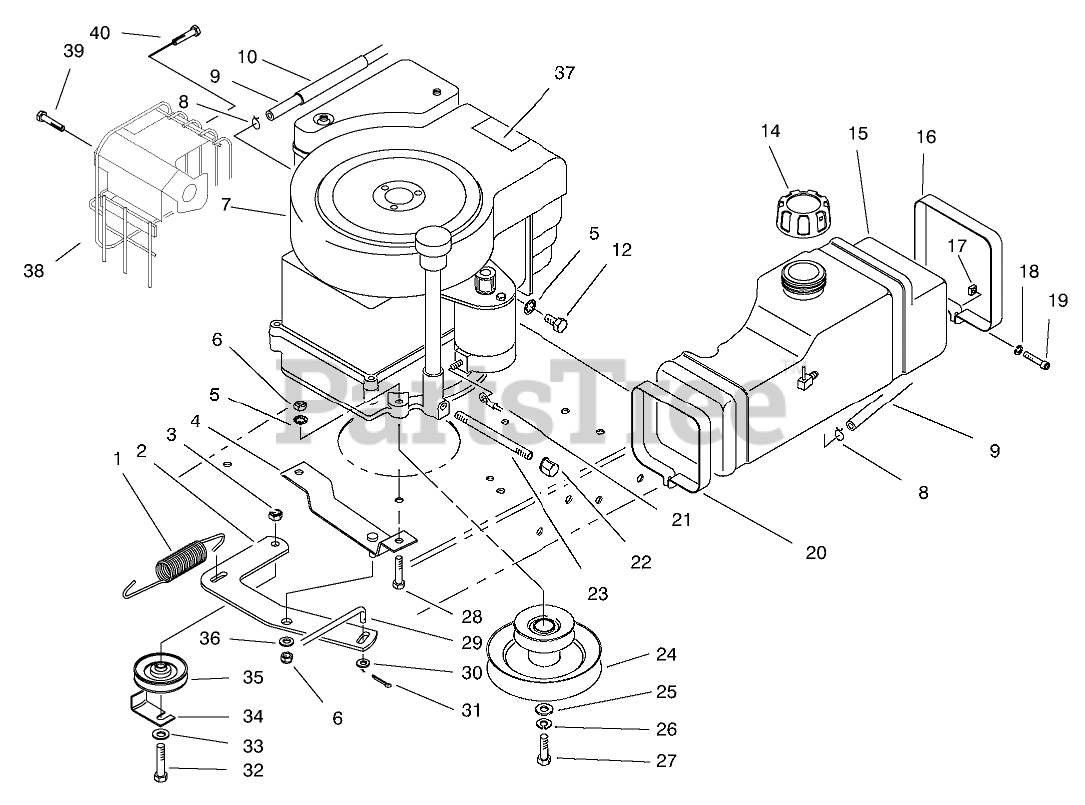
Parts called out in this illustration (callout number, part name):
1	SPRING-TRACTION
2	BRKT-TRACTION PIVOT
3	NUT-LOCK, NI
4	TRACT SUPT BRKT WA (BLACK)
5	WASHER-LOCK, INTERNAL
6	NUT-LOCK, NI
7	Engine-11.5 H .P.
8	CLAMP-HOSE
9	HOSE - FUEL
10	SUPPORT-FUEL LINE
12	SCREW-HWHTF
14	GAS CAP ASM
15	TANK-5 QT GAS
16	RETAINER-FRT TANK
17	NUT-SQUARE
18	WASHER-LOCK
19	SCREW-HSH
20	RETAINER-REAR TANK
21	WIRE ASM
22	CAP-PIPE
23	NIPPLE
24	PULLEY-ENGINE
25	WASHER-FLAT
26	WASHER-LOCK
27	SCREW-HH
28	SCREW-HH
29	ROD-TRACTION
30	WASHER-FLAT
31	PIN-COTTER
32	SCREW-HH
33	WASHER-FLAT
34	RETAINER-BELT
35	PULLEY-IDLER
36	WASHER-FLAT
37	DECAL - ENGINE
38	Guard-Muffler (Incl. Ref. #39 & 40)
39	SCREW 94887
40	SCREW 93587
